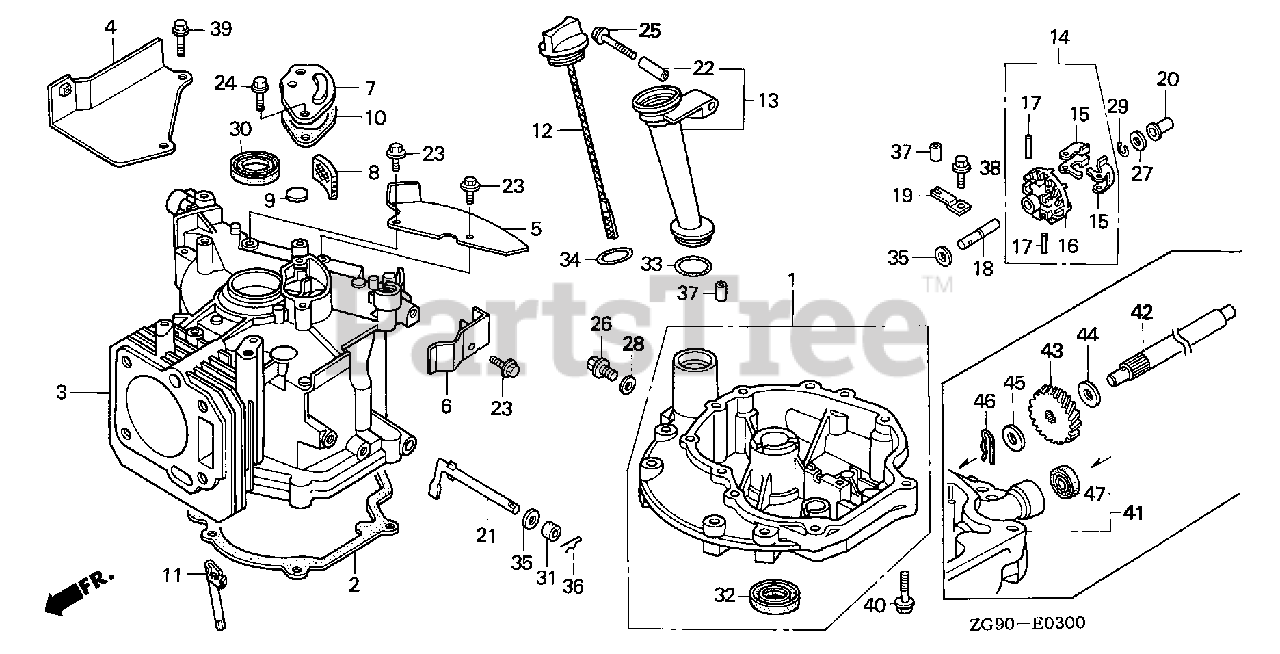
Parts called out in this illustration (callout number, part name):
1	PAN ASSY., OIL (KARCHER)
2	GASKET, OIL PAN
3	CYLINDER
4	PLATE, GUIDE
5	PLATE A, GUIDE
7	CAP, BREATHER CHAMBER
8	FILTER, BREATHER
9	VALVE, BREATHER
10	GASKET, BREATHER CHAMBER
11	PIPE, OIL DEFENSE
12	GAUGE, OIL LEVEL
13	EXTENSION, OIL FILLER
14	GOVERNOR ASSY.
15	WEIGHT, GOVERNOR
16	HOLDER, GOVERNOR WEIGHT
17	PIN, GOVERNOR WEIGHT
18	SHAFT, GOVERNOR HOLDER
19	PLATE, GOVERNOR SHAFT HOLDER
20	SLIDER, GOVERNOR
21	SHAFT, GOVERNOR ARM
22	COLLAR, EXTENSION
23	BOLT, FLANGE (6X12) (CT200)
24	BOLT, FLANGE (6X14) (CT200)
25	BOLT, FLANGE (6X32)
26	BOLT, DRAIN PLUG
27	WASHER, THRUST (6MM)
28	WASHER, DRAIN PLUG (10.2MM)
29	CLIP, GOVERNOR HOLDER
30	OIL SEAL (22X35X6)
31	OIL SEAL (6X11X4) (ARAI)
32	OIL SEAL (25X38X7)
32	OIL SEAL (25X38X7) (ARAI)
33	O-RING (22.1X2.2)
34	O-RING (26X2.7)
35	WASHER, PLAIN (6MM)
36	PIN, LOCK (8MM)
37	PIN, DOWEL (8X14)
38	BOLT, FLANGE (6X12)
39	BOLT, FLANGE (6X20)
40	BOLT, FLANGE (6X28)
